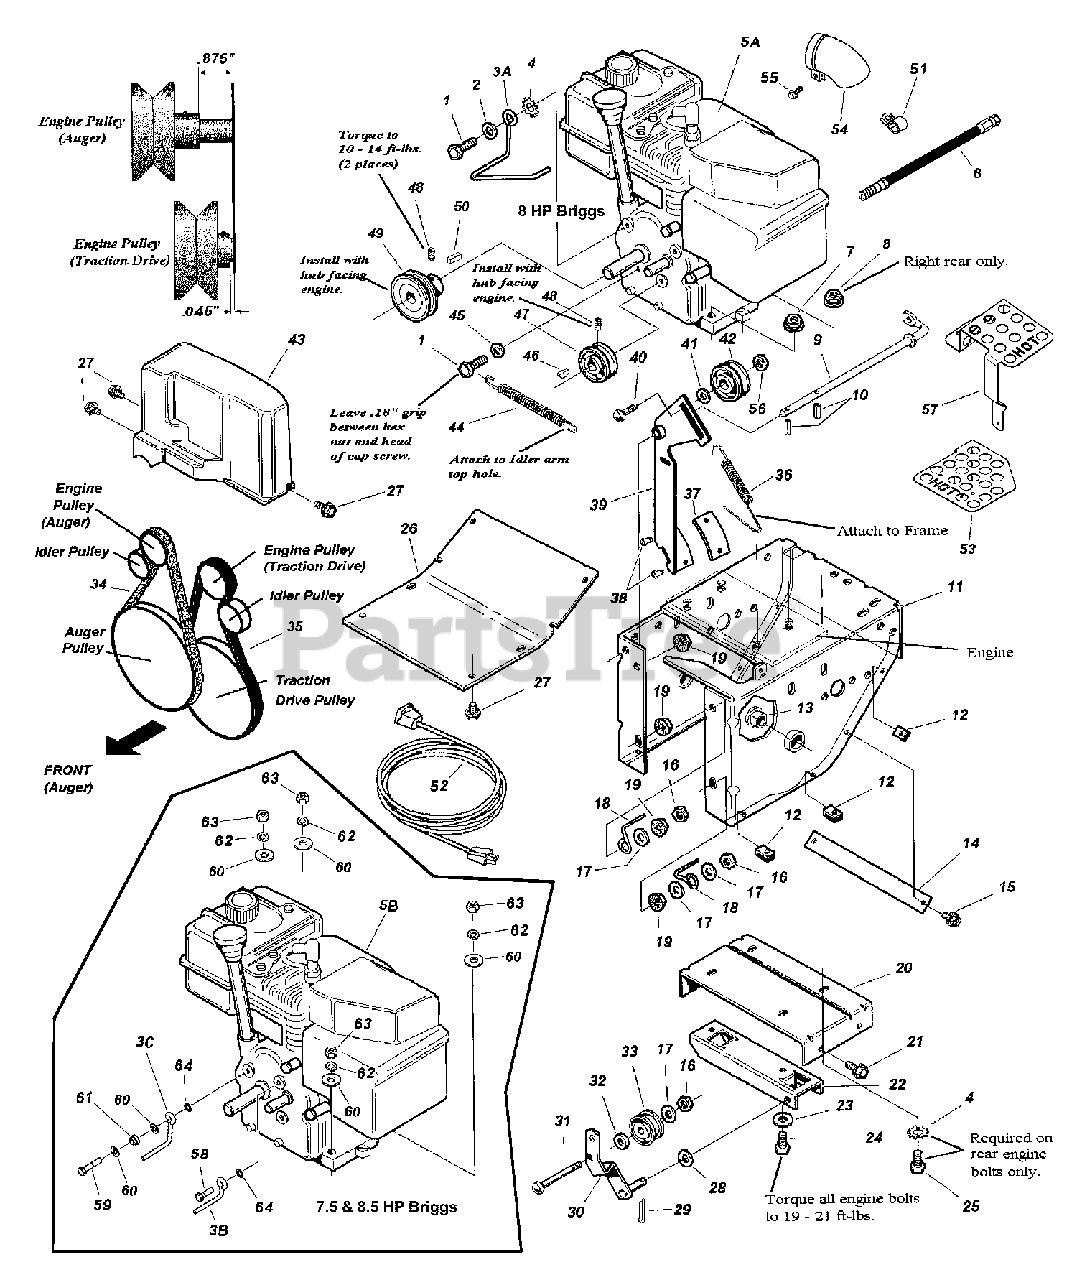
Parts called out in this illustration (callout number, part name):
1	SCREW, 5/16-24 x 1-1/4" Hex Head Cap, GR 5
2	WASHER, 5/16" Flat
3A	BELT STOP, Wire
3B	BELT GUIDE, LH, Traction Drive Belt
3C	BELT GUIDE, RH, Traction Drive Belt
4	LOCKWASHER, 5/16" Exterior Tooth
5A	* ENGINE, 8 HP B&S Mod. #12E394-0110-E1
5A	* ENGINE, 8 HP Intek (Metric) B&S Mod. #12E396-0111-E1
5B	* ENGINE, 7-1/2HP B&S OHV Mod. #12D196-0110-E1
5B	* ENGINE, 7-1/2HP B&S OHV Euro Mod. #12D296-0113-E1
5B	* ENGINE, 7-1/2HP B&S Euro Mod. #12D194-0114-E1
5B	* ENGINE, 7-1/2HP B&S Electric Start Mod. #12D194-0115-E1
5B	* ENGINE, 8-1/2HP B&S Intek ES Mod. #15B194-0110-E1
5B	* ENGINE, 8-1/2HP B&S Intek Mod. #15B196-0111-E1
6	HOSE, Oil Drain
7	NUT, 5/16-18 Hex Flange Lock- small
8	NUT, 5/16-18 Hex Flange Lock
9	ROD, Idler
10	ROLL PIN, 3/16 x 3/4"
11	WELDMENT, Intermediate Frame- Red
12	SPEED NUT, 1/4-20 U-Type
13	BUSHING, 1.00 long
14	SUPPORT, Tie Bar
15	SCREW, #10-24 x 1/2" Hex Washer Self-Tap
16	JAM NUT, 3/8-16 Hex Center Lock
17	WASHER, 3/8" SAE Flat
18	ROD, Belt Guide
19	NUT, 3/8-16 Hex Nyloc Heavy Thin
19	NUT, 3/8-16 Hex Nyloc
20	SUPPORT, Frame
21	SCREW, 5/16-18 x 1/2" Hex Washer Self-Tap
22	SUPPORT, Pivot
23	WASHER, 5/16" Flat
24	SCREW, 5/16-18 x 1-3/4 Hex Head Cap, GR 5
25	SCREW, 5/16-18 x 1-3/4 Hex Head Cap, GR 5
25	SCREW, 5/16-18 x 2" Hex Head Cap, GR 5
26	COVER, Bottom- Red
27	SCREW, 1/4-20 x 5/8" Hex Washer Self-Tap
28	WASHER, 7/16" Flat
29	COTTER PIN, 1/8 x 3/4"
30	WELDMENT, Idler Arm
31	BOLT, 3/8-16 x 1-1/4" Short Square Neck Carriage
32	SPACER, .377 ID x .75 OD x .312 Long
33	PULLEY, Idler
34	BELT, V Groove, 4L Sect.; 36.00" nom. effective length
35	V-BELT, 3L, 31.64 effective length
36	SPRING, Extension
37	PAD, Brake
38	RIVET, Blind
39	ASSEMBLY, Idler Arm w/Brake Pad
40	BOLT, 3/8-16 x 1-3/4 Short Square Neck Carriage, GR 5
41	WASHER, 3/8" Flat (.41 ID x 1.00 OD x .13 Thick)
42	PULLEY, Idler
43	COVER, Belt
44	SPRING, Extension, .562 OD x 4.250 Long x .049 Wire
45	JAM NUT, 5/16-24 Hex
46	KEY - Hi Pro .125 x .625 HP 504 SAE1035
47	PULLEY, V Groove
48	SET SCREW, 5/16-18 x 5/16" Hex Recess, Cup Point
49	PULLEY, 2.75 OD
50	KEY, 3/16x3/16x1"
51	HARNESS CLIP
52	CORD, Electric Start
53	GUARD, Muffler
54	DEFLECTOR, Muffler- B&S
55	HEX SCREW, Thread Rolling M4 x 0.7
56	NUT, 3/8-16 Hex Flange Lock Two Way
57	HEAT SHIELD, 7.5HP B&S Powerbuilt Muffler
58	SCREW, 5/16-24 x 1" Hex Head Cap, GR 5
59	SCREW, 5/16-24 x 1-1/2" Hex Head Cap, GR 5
60	WASHER, 5/16" Flat
61	BUSHING, Differential Link
62	WASHER, 5/16" Split Lock
63	NUT, 5/16-18 Hex, GR 5 or B
64	WASHER, 5/16" Internal Tooth Lock
